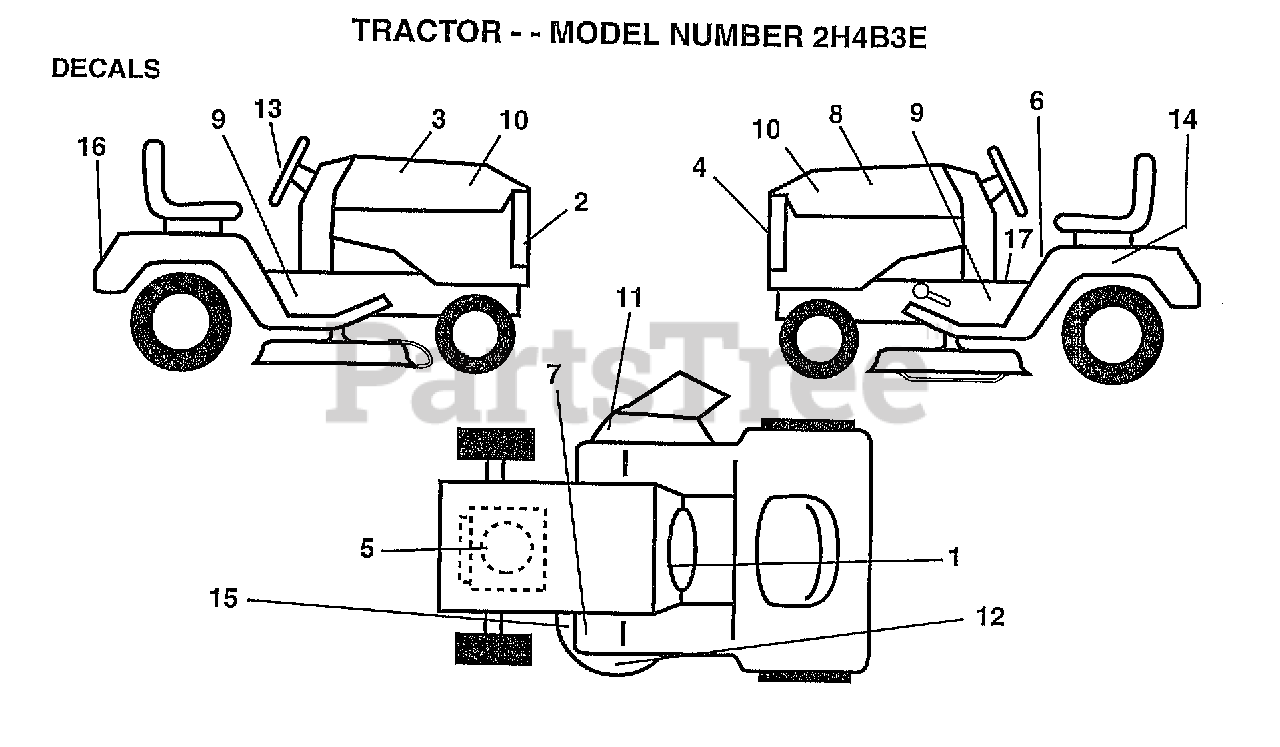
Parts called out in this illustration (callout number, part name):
1	DECAL.DASH.INSTR.
2	GRILL DECAL
3	DECAL HOOD RH RLY
5	DECAL, HP ENGINE
6	DECAL CAUTION
7	DECAL T
8	DECAL HOOD LH RLY
9	CHASSIS DECAL
11	"DECAL, WARNING"
13	"DECAL,STR WHL"
14	DECAL.BTRY.DANGER
15	DECAL
16	FENDER DECAL
17	DECAL BRAK PARK
